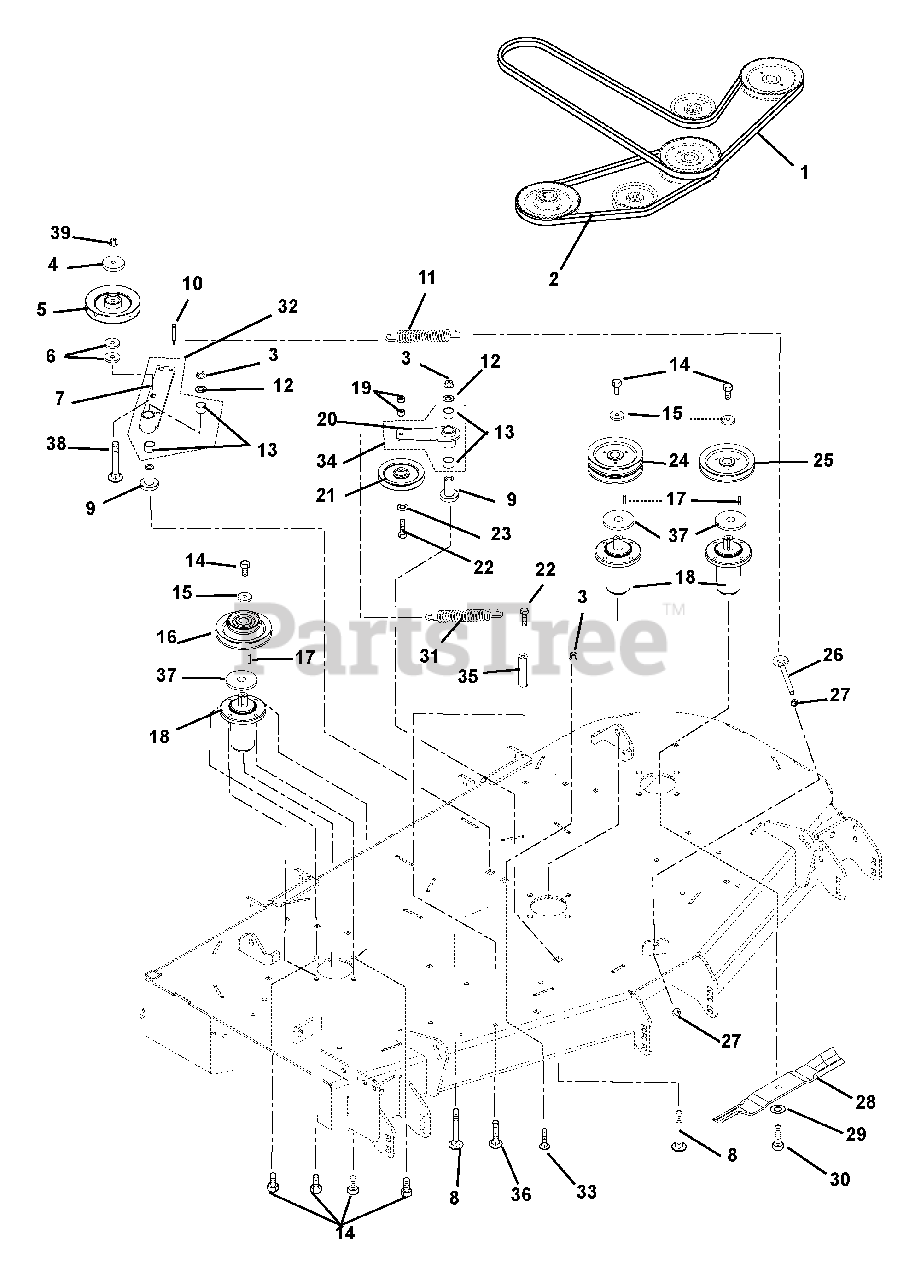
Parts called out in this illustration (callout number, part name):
1	Belt, 184.4" Long, PTO Drive Hex (992156)
1	Belt, 199" Long, PTO Drive Hex (992158)
2	V-Belt, 63" Long Cog B-Section (992156)
2	V-Belt,76"" Long Cog B-Section (992158)
3	Nut, .50-13 Nyloc Flange
4	Cap, Idler Bearing Sealing
5	Pulley, V 6.0 x .500 ID DBL. Bearing
6	Washer, Flat Steel .515 x 1.625 x .250
7	Idler, Pivot Arm
8	Bolt, Round Head Square Neck .50-13 x 3.50
9	Bearing, Pedestal
10	Bolt, Shoulder EP .38-16 x .30 Hex
11	Spring, Extension (Deck Idler)
12	Washer, Flat Steel .531x 1.250 x.100
13	Bearing, 1.00 x 1.12 x .75
14	Bolt, Hex .38-16 x 1.00
15	Washer, Flat Steel .406 x 1.50 x .245
16	Sheave, Double, 1" ID x 6.75" x 4.35" OD (992156)
16	Sheave, Double, 1" ID x 8.25" and 5.25" OD (992158)
17	Key, Square .25 x .25 x 1 RC 40-50
18	Spindle Assembly
19	Nut, Locking-Center .38-16
20	Idler, Pivot Arm
21	Sheave, .38" ID x 5" OD
22	Bolt, Hex .38-16 x 2.25
23	Washer, Flat Steel .406 x .812 x .065
24	Sheave, Double 1" ID x 6.75" OD (992156)
24	Sheave, Double 1" ID x 8.25" OD (992158)
25	Sheave, Single 1" ID x 6.75" OD (992156)
25	Sheave, Single 1" ID x 8.25" OD (992158)
26	Bolt, .38-16 x 4.50 .62 Diameter Eye
27	Nut, Hex, Jam .375-16
28	Blade, Mower (20.50") (992156)
28	Blade, Mower (24.50") without Tungsten Carbide Hardfacing (992158)
29	Washer, Bellville .63 x 1.625 x.14
30	Bolt, Hex .62-18 x 1.75 Grade 8
31	Spring, Extension
32	Assembly, PTO Idler Pivot Arm
33	Bolt, Round Head Square Neck .50-13 x 1.5, Full Thread, Grade 5
34	Assembly, Idler Pivot Arm
35	Nut, Coupling .375-16 x 1.75
36	Bolt, Round Head Square Neck .38-16 x 1.00
37	Retainer, Grease
38	Bolt, Round Head Square Neck .50-13 x 3.00 Grade 5
39	Nut, Locking, Center .50-13
